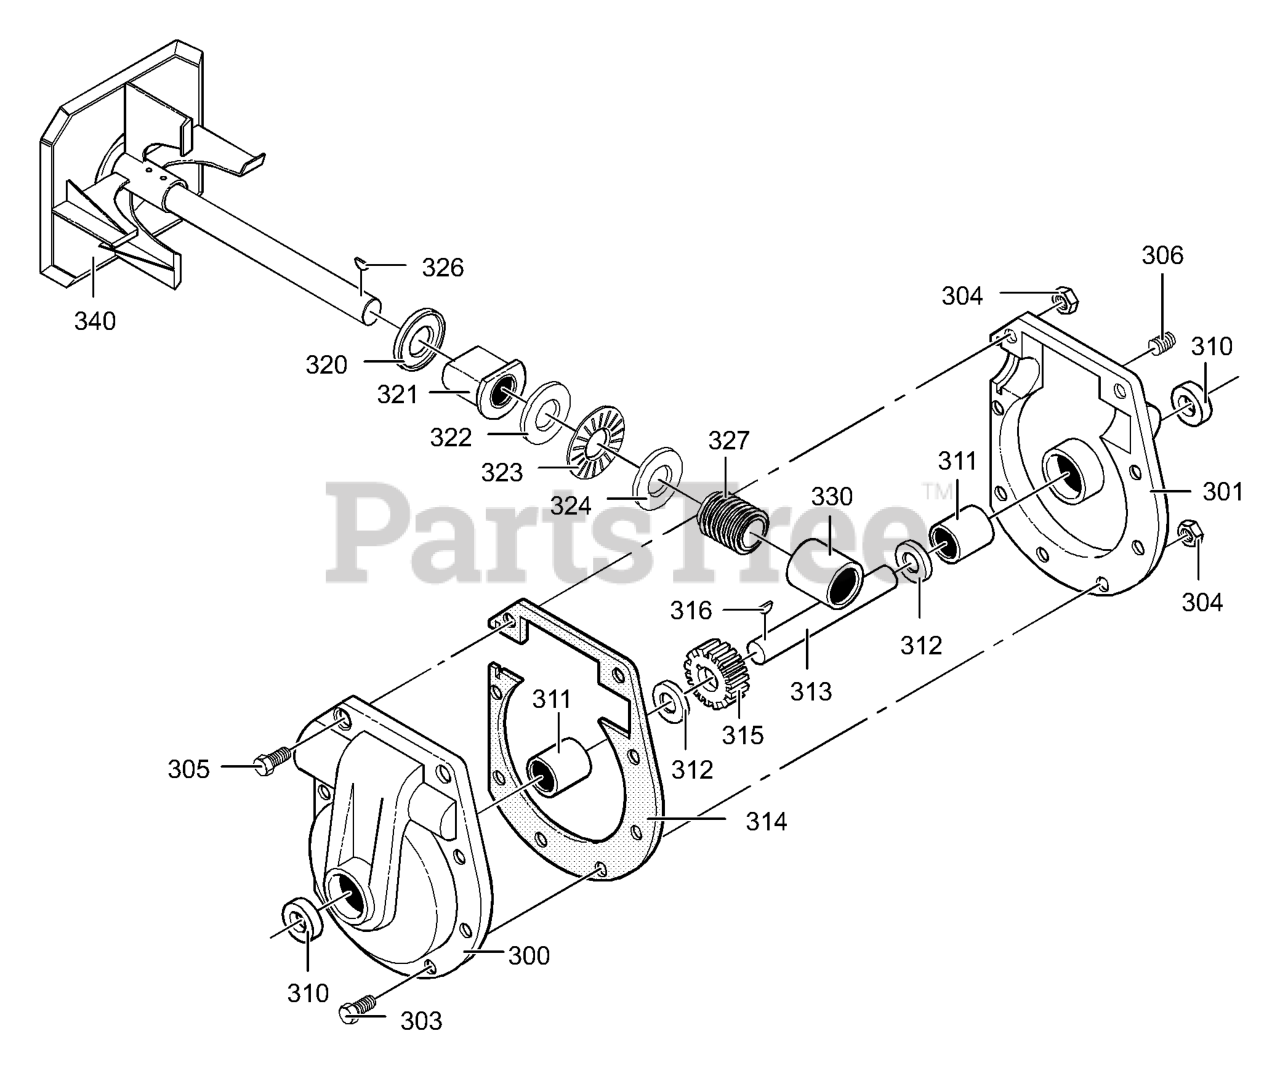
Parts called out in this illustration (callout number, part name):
300	CASE, GEAR, RH
301	CASE, GEAR, LH
303	SCREW, 5/16-24 x 1.00
304	NUT, 5/16-24
306	PIPE PLUG
310	SEAL, OIL
311	BEARING, SLEEVE
312	WASHER, FLAT 1.00 x 1.54 x .09
313	SHAFT, AUGER OUTPUT
314	GASKET, GEAR BOX
315	WORM GEAR
316	KEY, WOODRUFF #91
320	RING, QUAD
321	BEARING, FL
322	WASHER, FLAT
323	BEARING, ROLL
324	WASHER, FLAT
327	WORM GEAR
330	BEARING, SLEEVE
